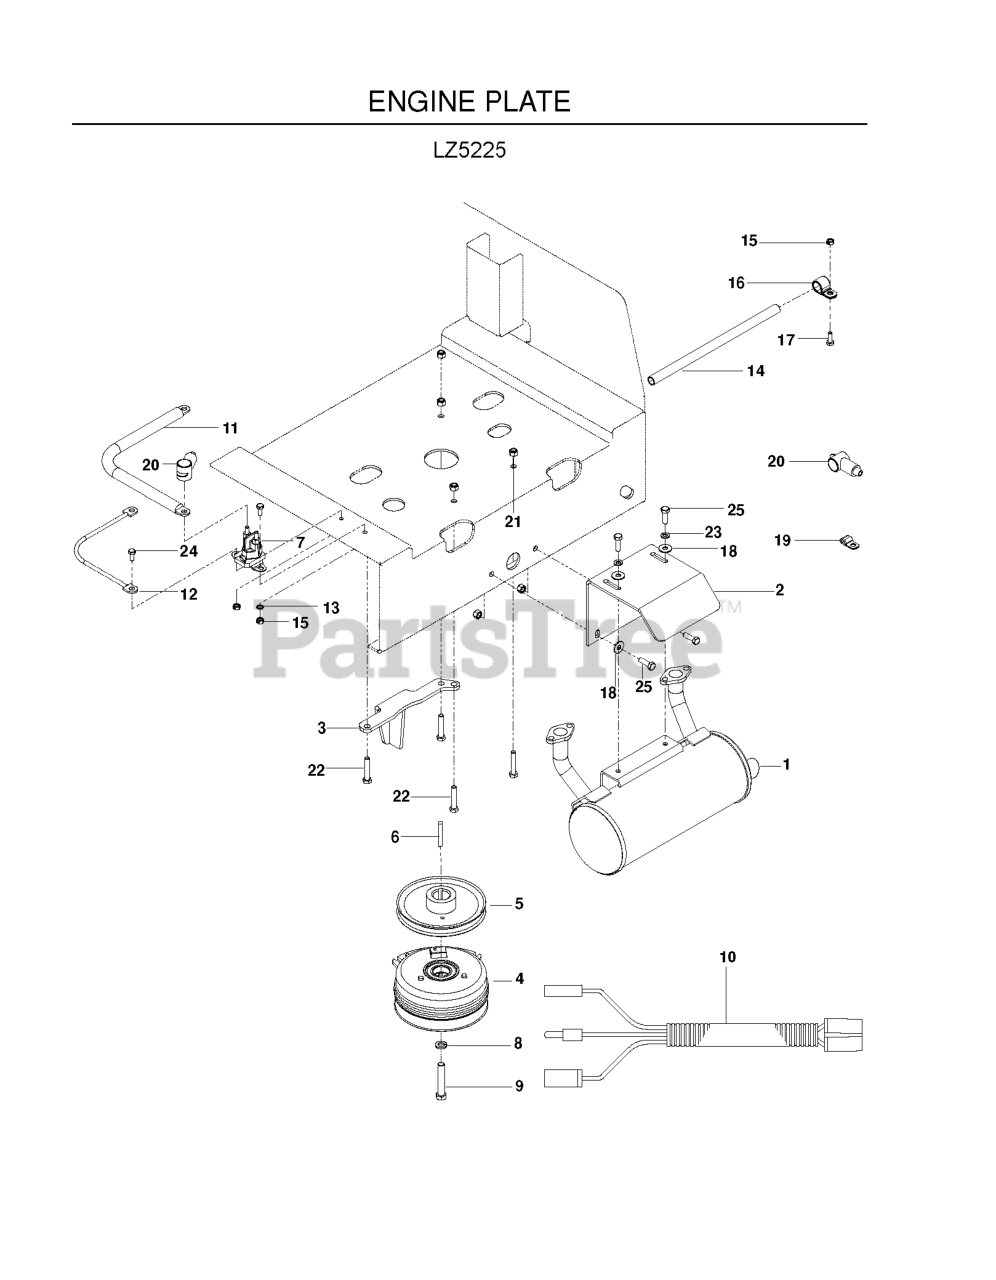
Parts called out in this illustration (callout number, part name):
1	MUFFLER KAWASAKI GEN II
2	MUFFLER BRACKET BLACK
3	WLDT, CLUTCH TIE DOWN BLK
4	ELECTRIC CLUTCH W/CABLE
6	KEY 1/4" SQ X 1 7/8"
8	WASHER 7/16 LOCK
9	BOLT 7/16F X 2 1/2
10	KAW PIGTAIL
11	CABLE POSITIVE
12	GROUND WIRE (KAW)
13	WASHER 1/4 INT TOOTH
14	OIL DRAIN HOSE
15	NUT 1/4C CENTER LOCK
17	HCS 1/4C X 3/4 HCS
18	WASHER 5/16 FLAT
19	DOUBLE TUBE CLAMP
21	NUT 5/16 NYLOC
22	HCS 5/16C X 1 3/4
23	WASHER.LOCK.HVY.HLCL.SPR.5/16
24	HCS 1/4C X 5/8
25	HCS 5/16C X 1
